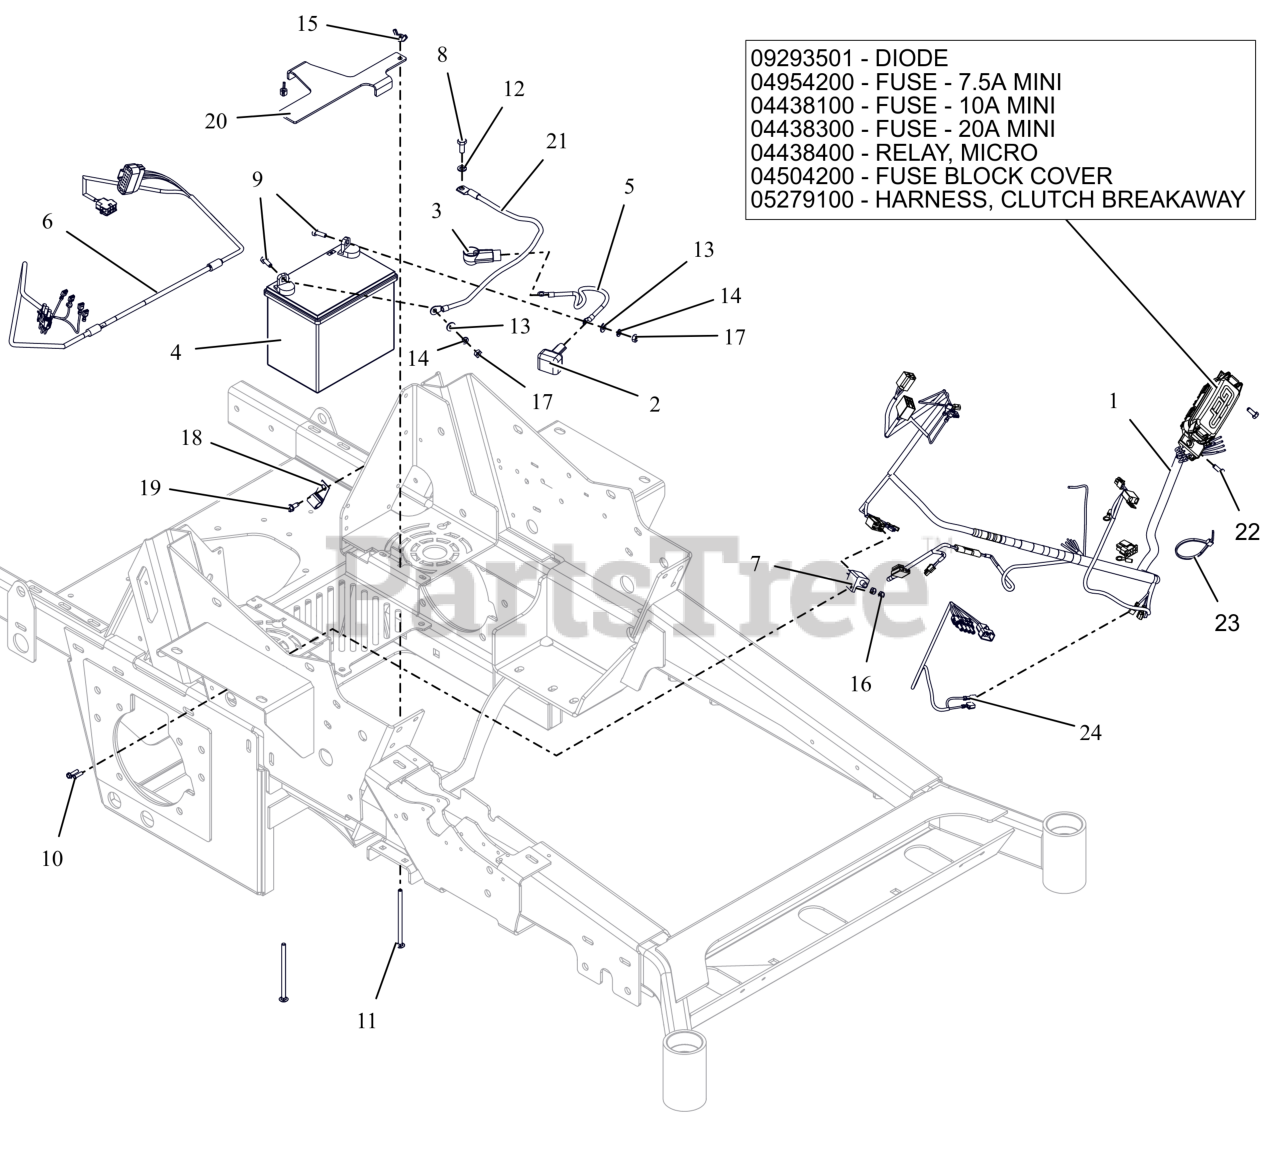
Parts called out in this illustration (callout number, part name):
1	HARNESS- WIRE PT300 MAIN
1	DIODE, CONNECTOR SHELL
1	FUSE, 7.5 AMP MINI-ATC
1	FUSE,10 AMP MINI-ATC
1	FUSE,20 AMP MINI ATC
1	RELAY,MICRO5 TERML W/RESISTOR
1	COVER, HARNESS FUSE/RELAY MOD
1	HARNESS, CLUTCH BREAKAWAY
2	INSULATOR
3	BOOT, .65ID POS
4	BATTERY, 300 CCA 10U1L
5	CABLE, STARTER 13.00"
6	HARNESS- EFI ENG ADAPTER PT300
7	SWITCH- DOUBLE POLE N.O./N.O.
8	BLT, HEX M8-1.25X20 G8.8 ZCC
9	BLT, HEX .25-20X.75 G5 ZCC
10	BLT, HWH #10-24X.75 ZCC
11	BLT, RHSN .25-20X4.50 G5 ZCC
12	WSHR,LK-REG .312X.078 ZCC
13	WSHR,FLT .281X.625X.065 ZCC
14	WSHR,LK-REG .250X.062 ZCC
15	NUT, LK-WING .25-20 ZCC
16	NUT-LK-NYL #10-24 G2 ZCC
17	NUT-STD .250-20 G2 ZCC
19	SCR,TAP .25-20X.625 HWH ZCC
20	HOLDDOWN- BATTERY
21	CABLE- NEG 16.00 IN
22	BLT, HEX M6-1X16 G8.8 ZCC
23	CABLE TIE, .15 X 8.50
24	HARNESS- AIR RIDE SEAT
